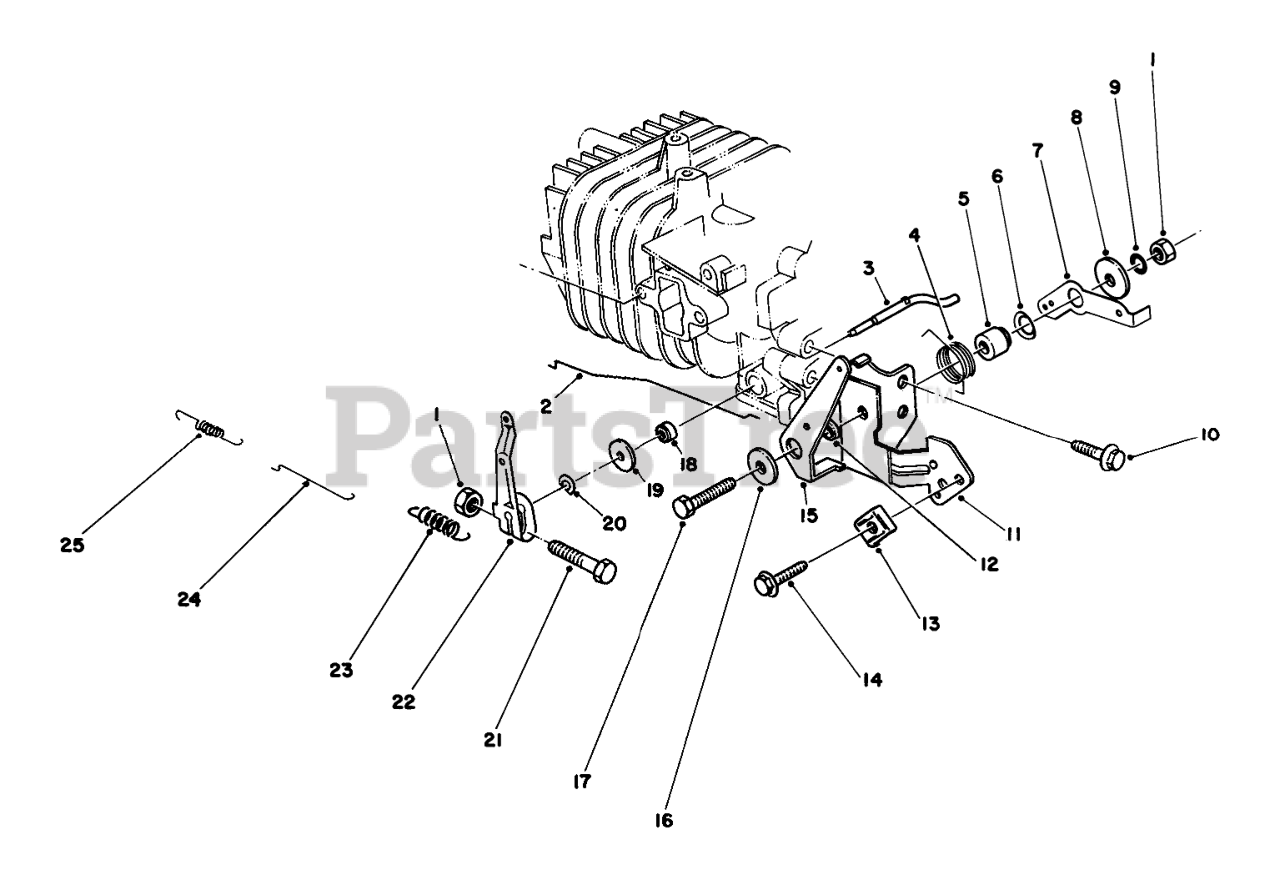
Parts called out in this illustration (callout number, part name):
2	CHOKE ROD
3	Shaft-Govemor
4	SPRING-CHOKE LEVER
5	Gov Lever Spacer
6	Washer-Gov. Spring Lever
7	GOV SPRING LEVER
8	WASHER
9	LOCKWASHER
11	BRACKET-THROTTLE, CONTROL
12	SPACER-CHOKE LEVER
13	CLAMP
15	LEVER-CONTROL, CHOKE
16	WASHER
18	SEAL-OIL
19	WASHER
20	E-RING
22	Lever-Throttle Control
23	GOVERNOR SPRING
24	ROD-CARBURETOR
25	SPRING
